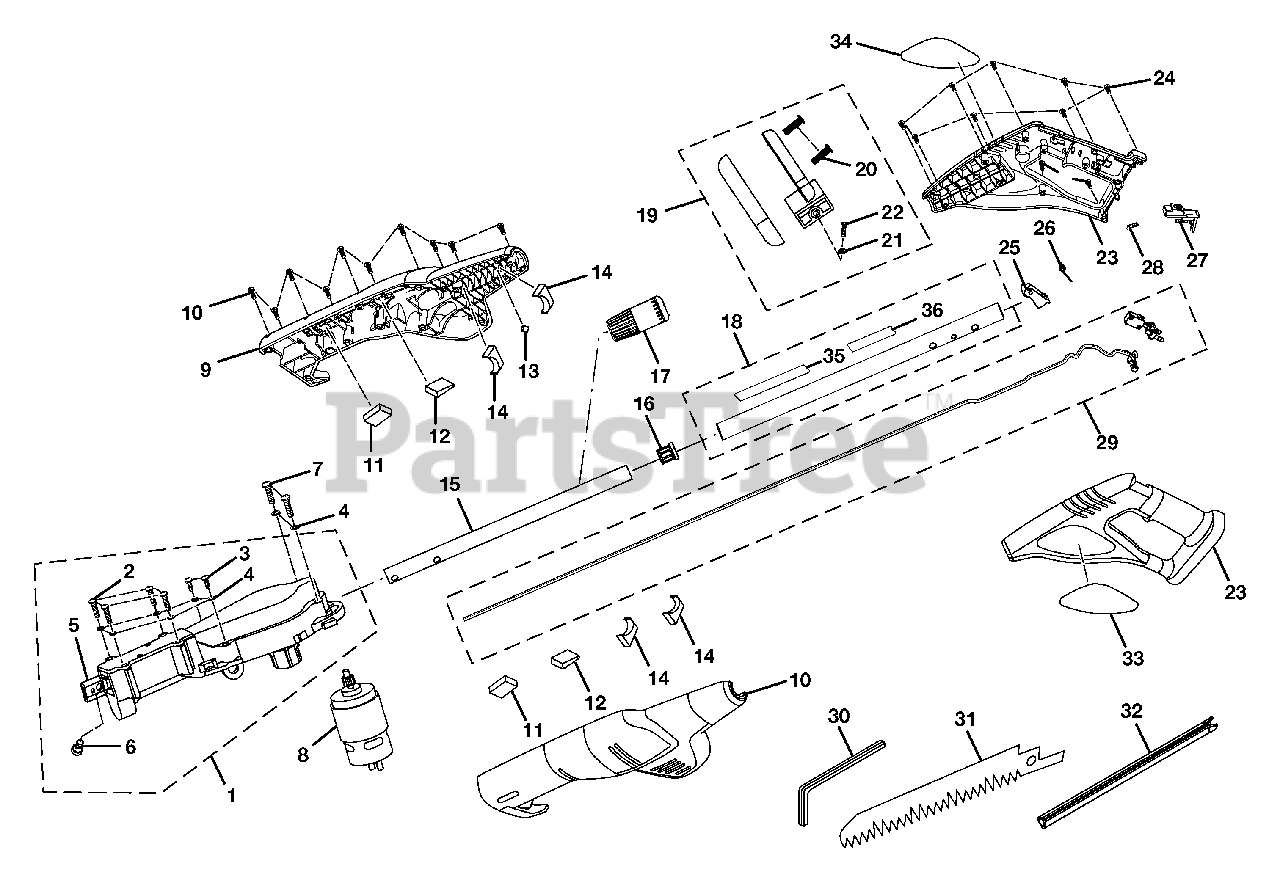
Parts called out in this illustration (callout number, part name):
1	GEAR BOX ASSEMBLY
2	SCREW (M4 X 18 mm)
3	SCREW (M4 X 12 mm)
4	SPRING WASHER
5	MOUNTING CLAMP
6	SCREW (M6) WITH SPRING
7	SCREW (M4 X 28 mm)
8	MOTOR ASSEMBLY
9	MOTOR HOUSING ASSEMBLY
10	SCREW (M4 X 16 mm)
11	FRONT ISOLATION BLOCK
12	CENTERISOLATION BLOCK
13	RUBBERSEAL
14	REARISOLATION BLOCK
15	UPPER SHAFT (23 mm X 613mm)
16	TUBE STOPPER
17	CONNECTING CAP ASSEMBLY
18	TUBE ASSEMBLY (26 mm X 584
19	HANDLE ASSEMBLY
20	SCREW (M3 X 14 mm)
21	HEX NUT (M6)
22	SCREW (M6 X 10)
23	HOUSING ASSEMBLY
24	SCREW (M3.5 X 16 mm)
26	TRIGGER SPRING
27	TRIGGER LOCK
28	COMPRESSION SPRING
29	SWITCH ASSEMBLY
30	HEX KEY (5 mm)
32	BLADE COVER
33	LOGO LABEL
34	DATA LABEL
35	WARNING LABEL
36	DATA WARNING LABEL
